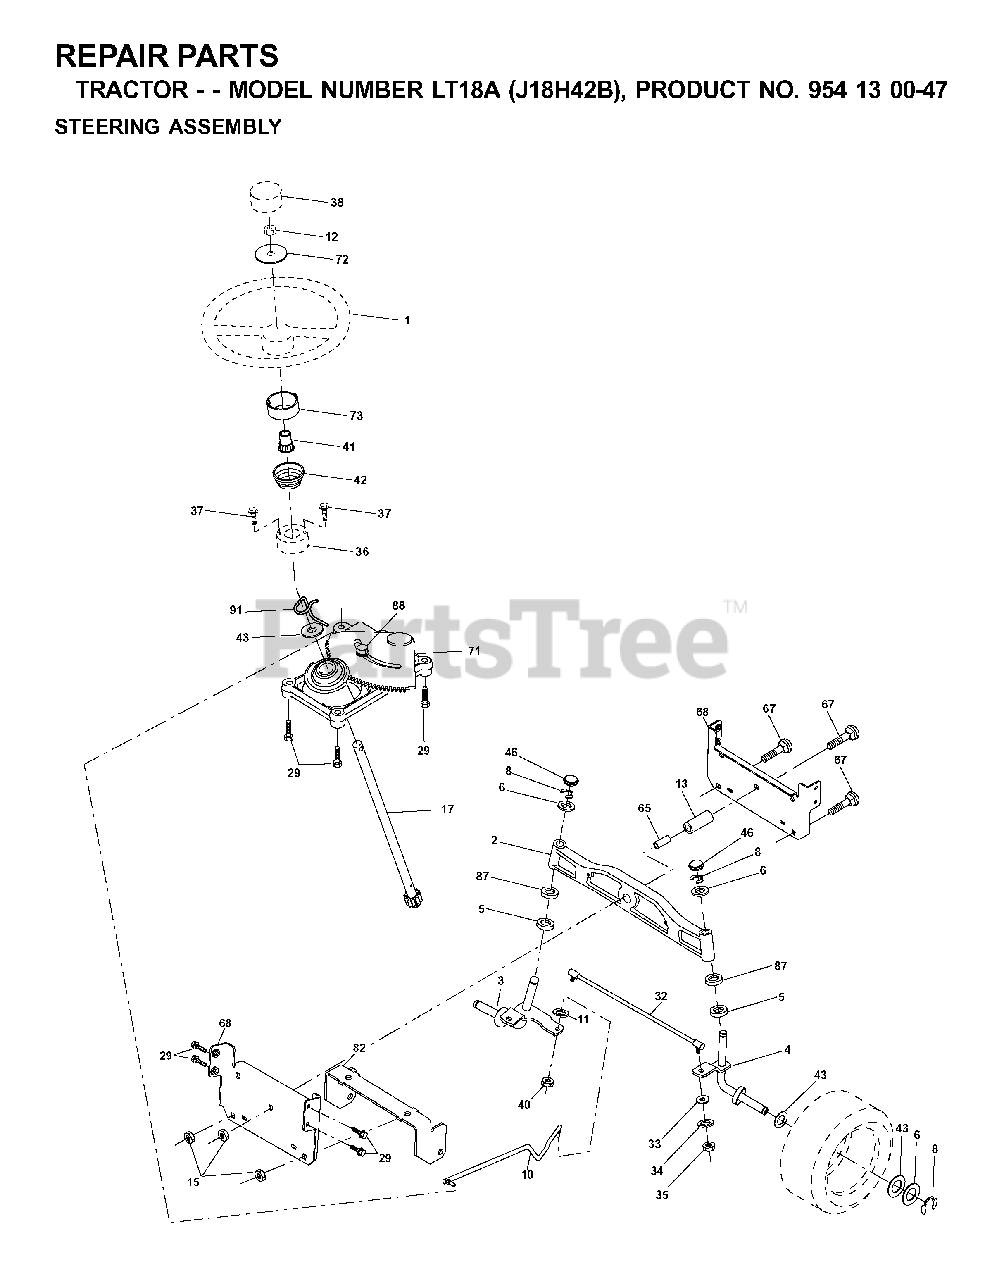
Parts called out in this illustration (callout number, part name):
2	AXLE ASM
3	SPINDLE.ASM.LH.15"TIRES
4	SPINDLE.ASM.RH.15"TIRES
8	RING CLIP
10	DRAGLINK.15".TIRES.2001
11	WASHER, LOCK 3/8
12	NUT.HEX.1/2-20
13	TUBE, PIVOT AXLE
15	NUT
17	SHAFT ASM STRG
29	SCREW 3/8-16X3/4
33	WASHER M
34	LOCKWASHER
35	NUT, CROWNLOCK
36	BUSHING, STRG. BLK
40	GRIPCO NUT
41	STEERING WHEEL ADAPTOR
46	CAP.SPINDLE
65	SPACER BRACE AXLE
67	BOLT
68	BRACE.AXLE.15"TIRES
71	STEERING ASM
82	BRACKET
87	WASHER, FLAT .781 X 1 1/2"
88	BOLT, SHOULDER 7/16-20
91	CLIP.STEERING
